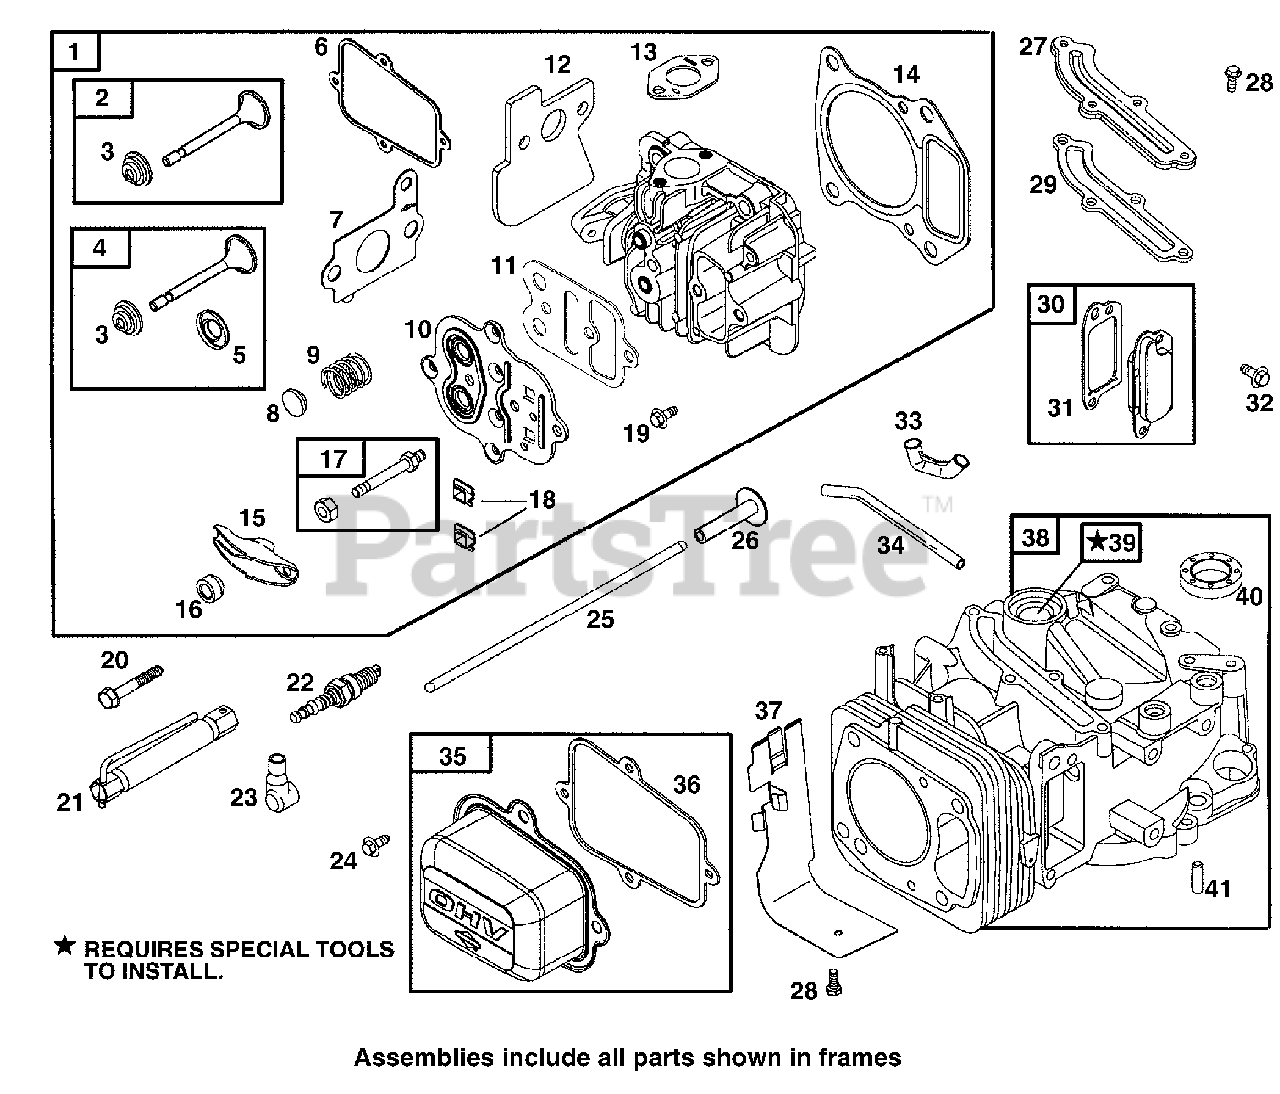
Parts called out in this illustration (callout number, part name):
1	Cylinder Head
2	Exhaust Valve
3	Valve Retainer
4	Intake Valve
5	Valve Seal
6	Rocker Cover Gasket
7	Intake Gasket
8	Valve Cap
9	Valve Spring
10	Cylinder Head Plate
11	Plate Gasket
12	Carburetor Spacer
13	Exhaust Gasket
14	Cylinder Head Gasket
15	Rocker Arm
16	Rocker Arm Ball
17	Rocker Arm Stud
18	Push Rod Guide
19	Hex Screw
20	Hex Screw
21	Spark Plug Wrench
22	Spark Plug
23	Spark Plug Boot
24	Hex Screw
25	Push Rod
26	Valve Tappet
27	Breather Passage Cover
28	Hex Screw
29	Breather Passage Gasket
30	Breather Assembly
31	Breather GAsket
32	Hex Screw
33	Grommet
34	Breather Tube
35	Rocker Cover
36	Rocker Cover Gasket
37	Cylinder Shield
38	Cylinder Assembly
39	Bushing/Seal Kit
40	Oil Seal
